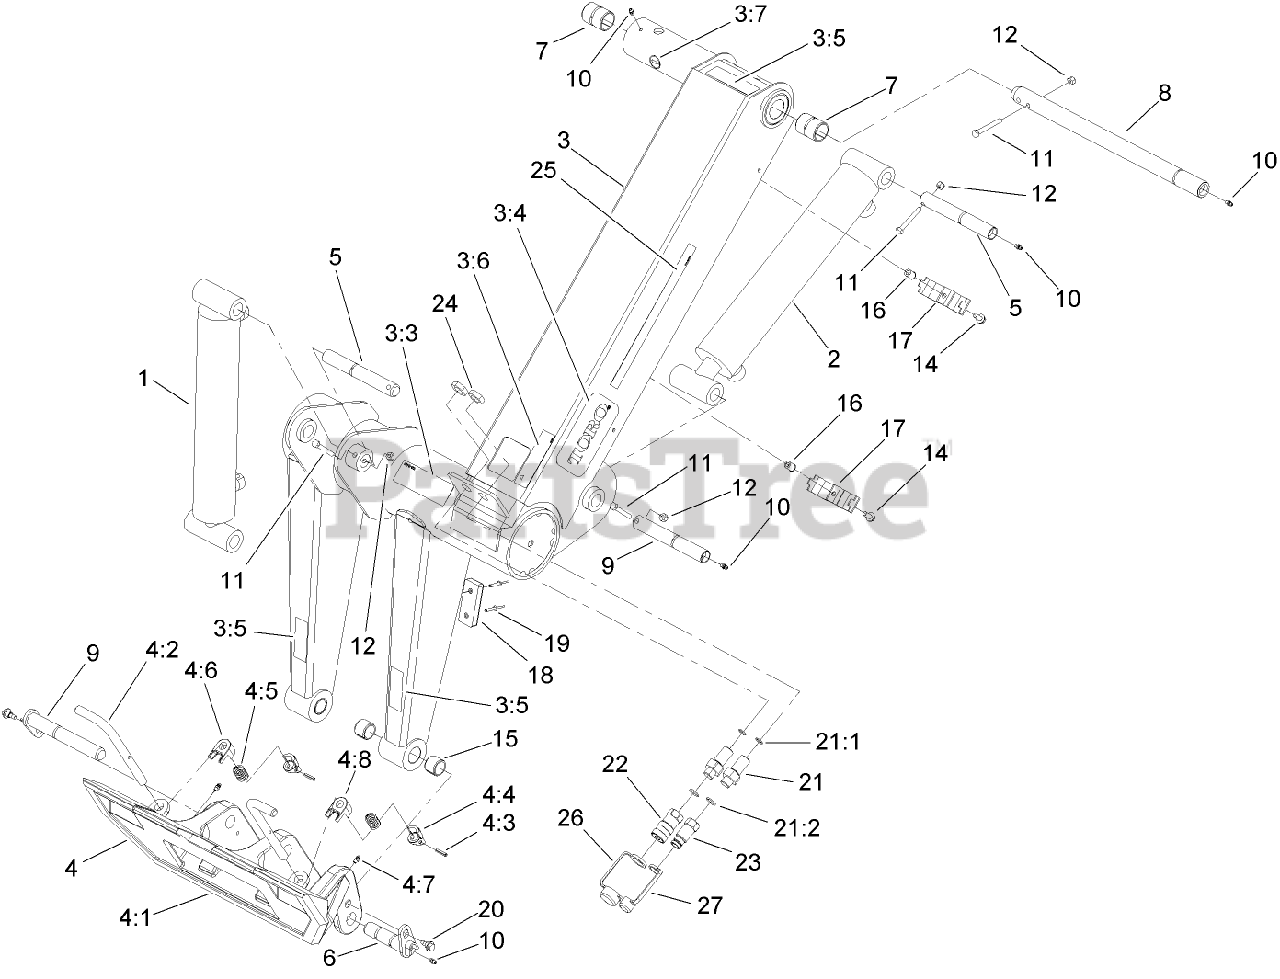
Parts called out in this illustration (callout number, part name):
1	CYLINDER-HYD
2	CYLINDER-HYD
3	LOADER ARM ASM
3:3	DECAL-CAUTION
3:5	DECAL-PINCH
3:6	DECAL-CAUTION
3:7	DECAL-GREASE
4	QUICK ATTACH ASM
4:1	MOUNT-QTACH
4:2	PIN-LOCKING
4:3	PIN-GROOVED
4:5	SPRING-COMPRESSION
4:6	STOP-RH
4:7	FITTING-GREASE
4:8	STOP-LH
5	PIN-PIVOT
6	PIVOT PIN ASM
7	BUSHING-TENSION, LOADER ARM
8	PIN-PIVOT, LOADER ARM
9	PIVOT PIN ASM
10	FITTING-GREASE
11	SCREW-HH
12	NUT-LOCK, NI
14	SCREW-HH
15	BUSHING-TENSION
16	NUT-INSERT
17	CLAMP-HOSE
18	BUMPER-RUBBER
19	RIVET-POP
20	BOLT-SHOULDER
21	UNION-BULKHEAD
21:1	O-RING
21:2	O-RING
22	COUPLER-FEMALE
23	NIPPLE-CONNECTOR
24	NUT-BULKHEAD
25	DECAL-MODEL
26	CAP-DUST
27	PLUG-DUST
